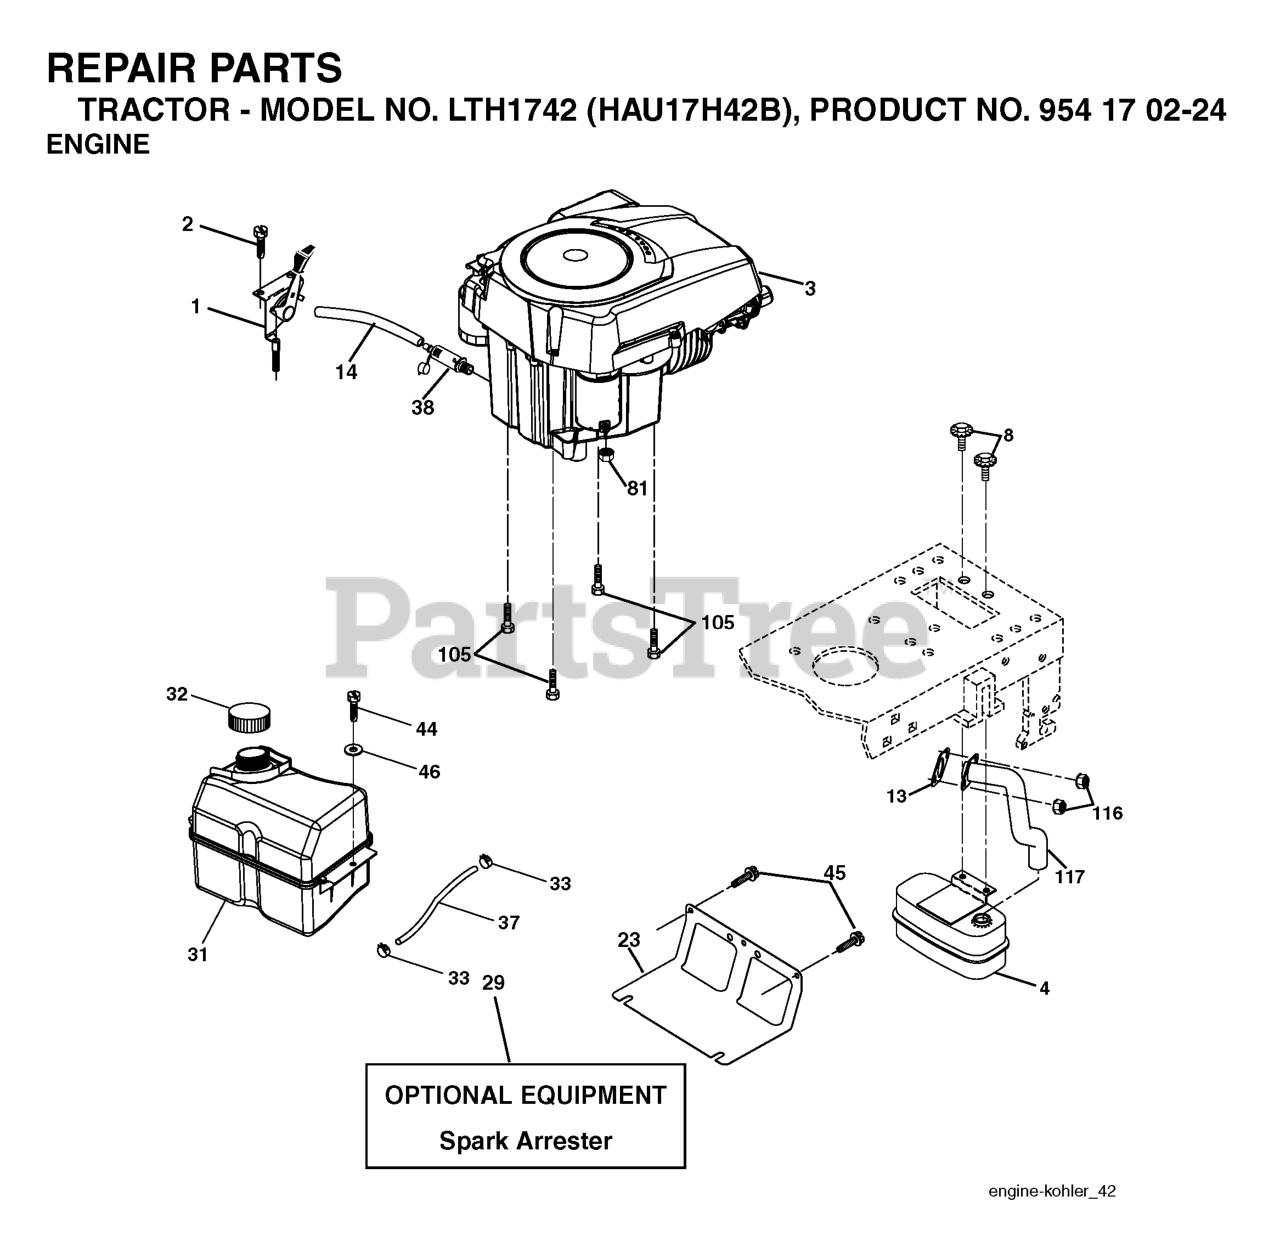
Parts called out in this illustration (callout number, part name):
1	CONTROL.THROTTLE.LT/YT
2	SCREW
4	MUFFLER.SINGLE.CYL.KOHL/B&S
8	BOLT.5/16-18UNCX3/4 W/SEMS.BLK
13	GASKET.EXHAUST.KOHLER
14	TUBE, DRAIN OIL ASM.
23	SHIELD.BROWNING.DBR.GUARD
29	KIT.SPARK ARRESTOR 794945 B&S
31	TANK FUEL
32	FUEL CAP
33	HOSE CLAMP
37	LINE.FUEL.20
38	PLUG DRAIN OIL EASY
44	SCREW HEXWSHR 1/4-20X3/4
45	SCREW, 3/8-16X3/4
81	NUT
105	SCREW 3/8-16X1
116	NUT.HEX.FLANGE.TOPLOCK
117	RP.TUBE.EXHAUST.KOHL.COURAGE
